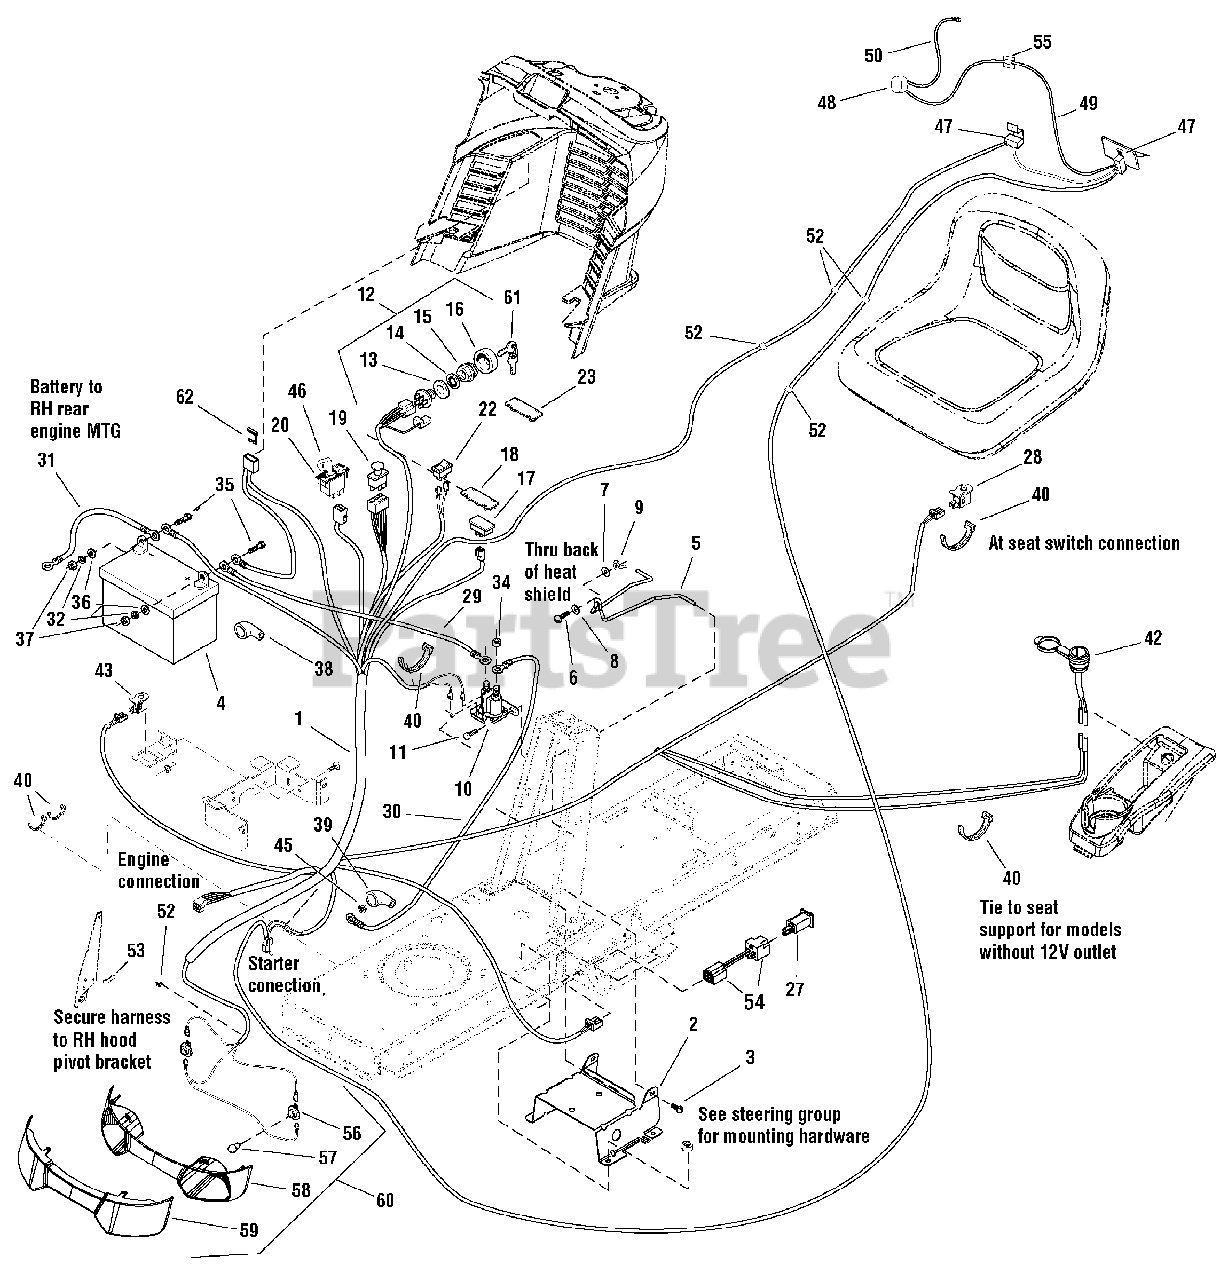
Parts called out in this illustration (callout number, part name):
1	HARNESS, Main
2	SUPPORT, Battery
3	SCREW, Hex Washer Head, TAPTITE, 5/16-18 x 5/8
4	BATTERY, 12V 230 CCA DRY
5	HOLD DOWN, Battery
6	BOLT, Carriage, 1/4-20 x 7/8
7	WASHER, Flat .25
8	PUSHNUT, 1/4
9	NUT, 1/4 ESNA
10	SOLENOID, 12V
11	SCREW, Hex Washer Head, TAPTITE, 1/4-20 x 1/2
12	SWITCH ASSEMBLY, Ignition
13	WASHER, 5/8
14	WASHER, Lock, Int. Tooth .62
15	NUT, Hex Flange, 5/8, IGN Switch
16	COVER, Ignition Switch
17	HOUR METER
18	PLUG, Hour Meter
19	SWITCH, PTO
20	SWITCH, RMO Module Only
22	SWITCH, Head lights
23	PLUG
27	SWITCH, Push (Foot Pedal)
28	SWITCH, Push NC (Seat)
29	CABLE, #6 10.0 Lg Red
30	CABLE, #6 25.0 Lg Red
31	CABLE, #6 20.0 Lg Black
32	LOCKWASHER, Spring 1/4
34	NUT, Hex KEPS Lock, 5/16-24
35	CAPSCREW, Hex, 1/4-20 x 3/4
36	WASHER, Flat, 1/4
37	NUT, Hex, 1/4-20
38	BOOT, Insulator, Battery
39	BOOT, Insulator, Red
40	TIE, RT 360 /L=150
42	12V AUX. PLUG, With Cover
43	SWITCH, Push Button, NO, Black
45	NUT, Flange, Whiz, 1/4-20
46	KEY, RMO Module
47	MICROSWITCH, MKH 12 D13 S1
48	BEEPER, PF 27 A 29 EP/
49	WIRE, 9-8316-616
50	WIRE, 9-8316-615
52	CABLE, Clip WSBH 1-0-1
53	CLIP, Speed Wire
54	PLUG, Shut-Off
55	CLIP, Cable WCK 460 01/A
56	SOCKET ASSEMBLY
57	BULB, 1141-12V 21CP
58	REFLECTOR, Headlight
59	LENS, Headlight
60	HEADLIGHT ASSEMBLY
61	KEY, Ignition (Set of 2)
62	FUSE
